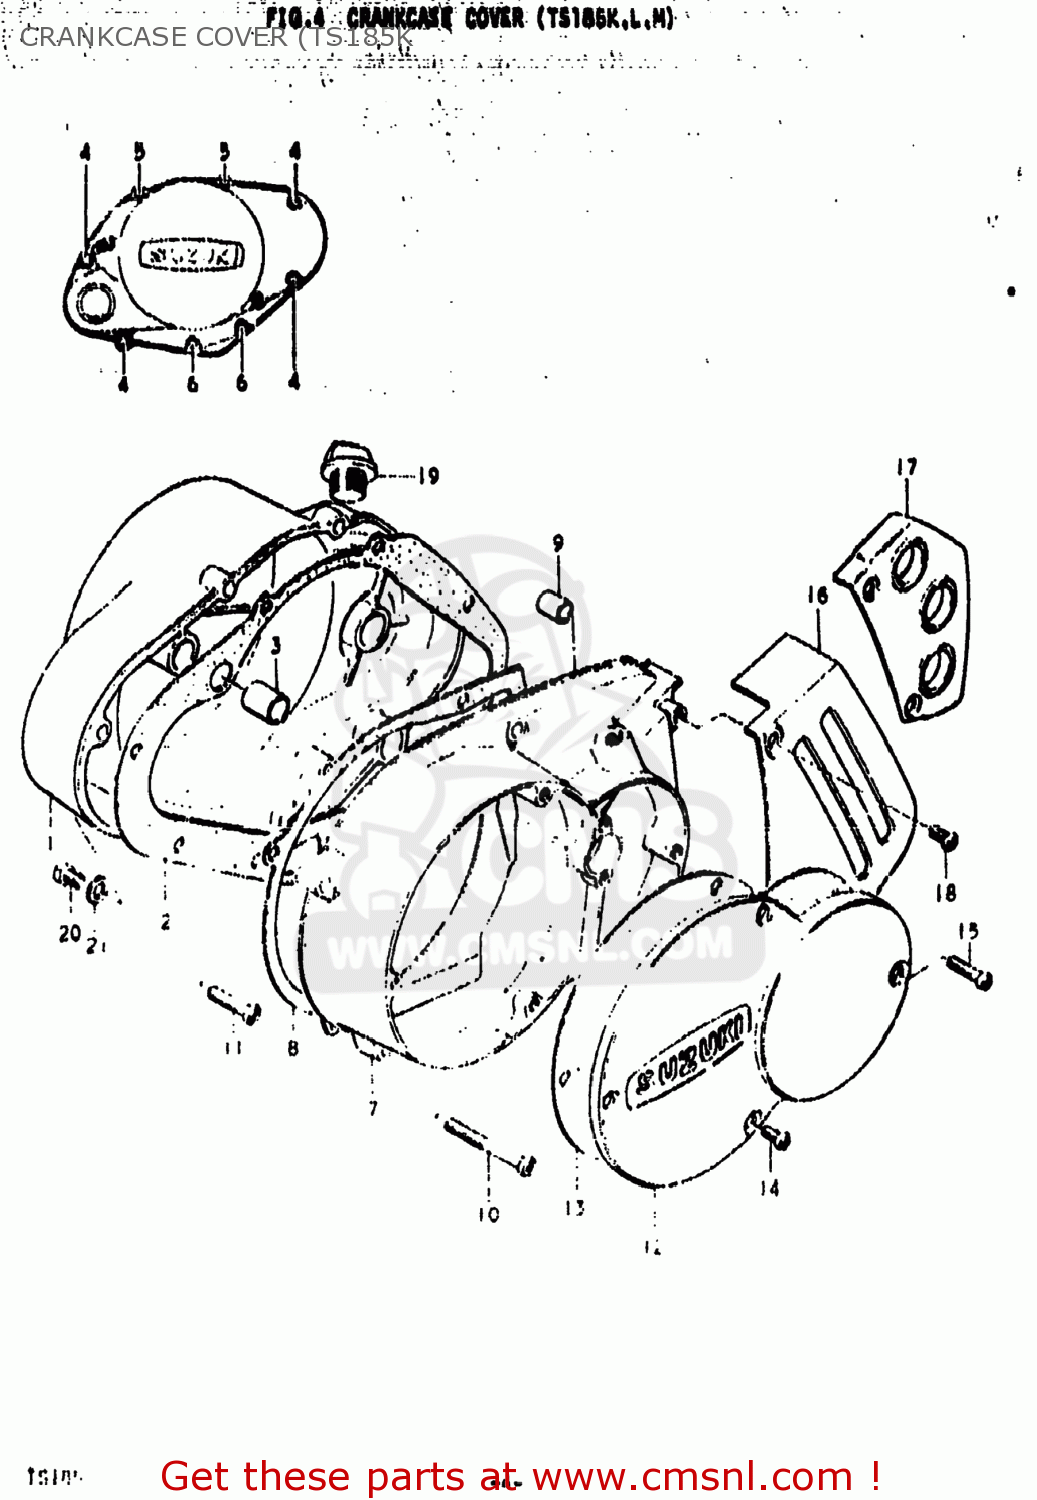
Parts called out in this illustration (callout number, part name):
1	COVER,CLUTCH
2	GASKET,CLUTCH COVER (AS (MCA)
3	PIN
4	SCREW
5	SCREW
6	SCREW
7	COVER
8	GASKET,MAGNETO COVER (MCA)
9	PIN
10	SCREW
11	SCREW
12	CAP,MAGNETO INSPECTION
13	GASKET,MAGNETO INSPECTION (MCA)
14	SCREW
15	SCREW
16	COVER,SPROCKET
17	COVER,SPROCKET
18	SCREW
19	PLUG
20	SCREW(6X10)
21	GASKET(6.2X11X1) (NAS)
